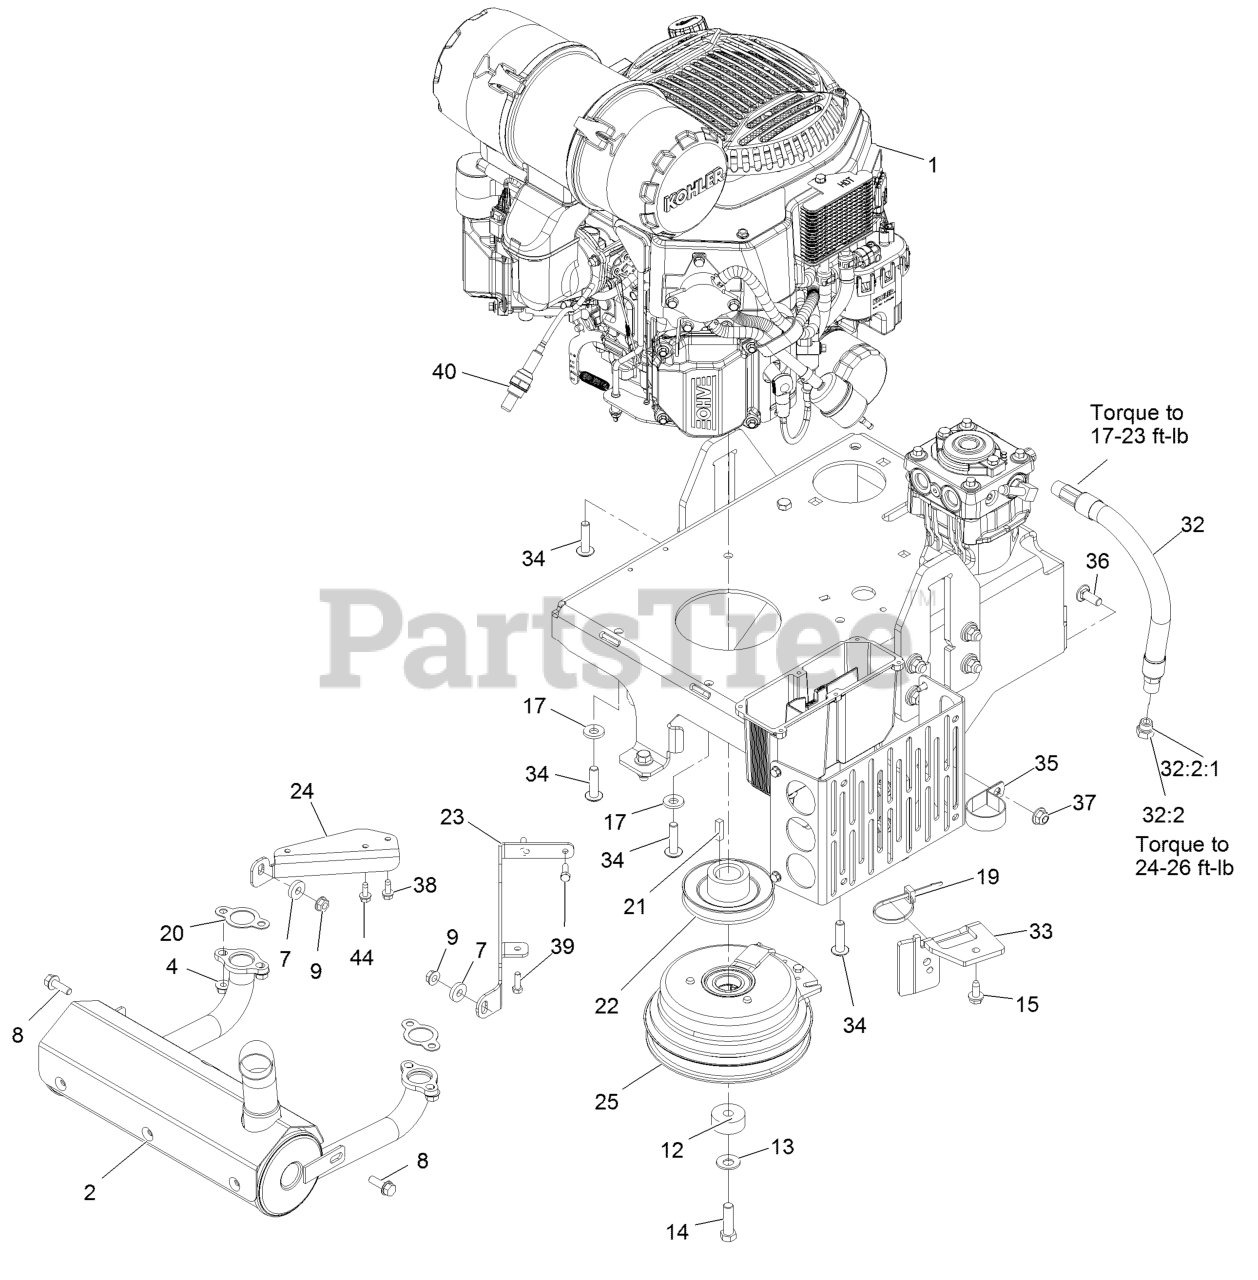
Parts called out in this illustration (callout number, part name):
4	NUT-FLANGE
8	SCREW-HHF
12	KEEPER-CLUTCH
13	WASHER-SPRING
14	SCREW-HH
15	Screw-HWH 5/16-18 X 3/4 Tf
17	WASHER-BELLEVILLE
19	TIE-CABLE
20	GASKET-EXHAUST
23	MOUNT, MUFFLER-LT
24	MOUNT, MUFFLER-RT
25	CLUTCH-200 FT-LB, 1.125 B
32	OIL DRAIN HOSE ASM
32:2	PLUG-HH
32:2:1	O-RING
33	BRACKET-ANCHOR, CLUTCH
34	SCREW-BHTF
35	CLAMP-R
36	SCREW-CARR
37	NUT-HF, NI
38	SCREW-HWHTF
39	SCREW-HH M6-1 X 20Mm W/Patch
40	SENSOR-OXYGEN
44	SCREW-HWHTF
